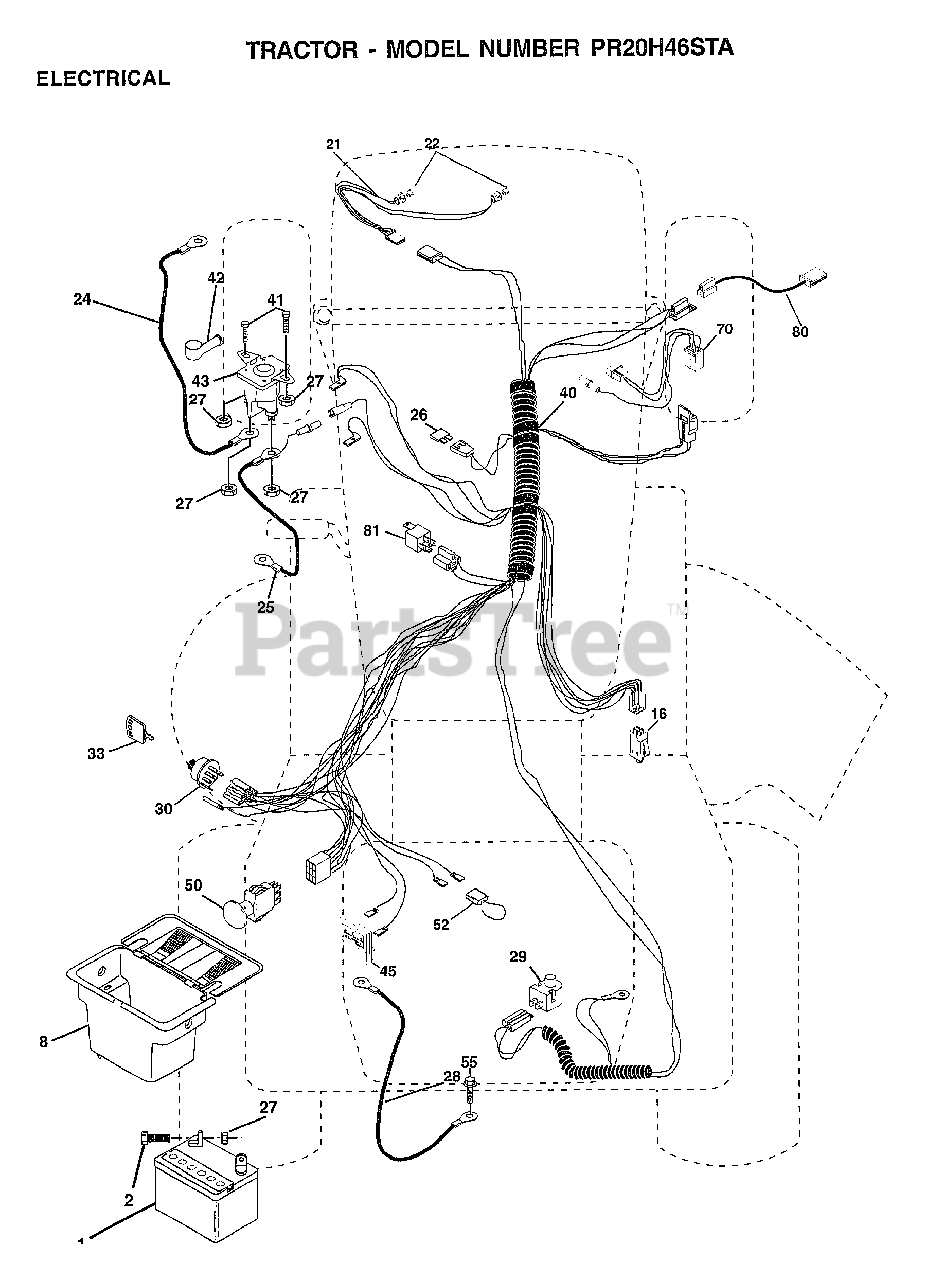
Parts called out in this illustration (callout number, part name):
2	BOLT LT
8	"TRAY T, BATTERY"
11	HOLDDOWN BATTERY
16	SWITCH INTERLOCK
21	HARNESS.ASM.LIGHT W/4152J
22	HEADLAMP BULB
24	"CABLE T, BATTERY"
25	CABLE.6GA.22W/16W
26	FUSE.15 AMP
27	NUT
28	CABLE.GRND.6GA.21
29	SWITCH.PLUNGER
30	SWITCH.IGN.
33	KEY MLD GEN DELTA
40	HARNESS IGN
41	BOLT HXHD FIN
45	AMMETER
52	PROTECTION LOOP
55	SCREW LT
70	HARNESS
80	HARNESS.CLUT.EVX.
81	RELAY ASSY T
